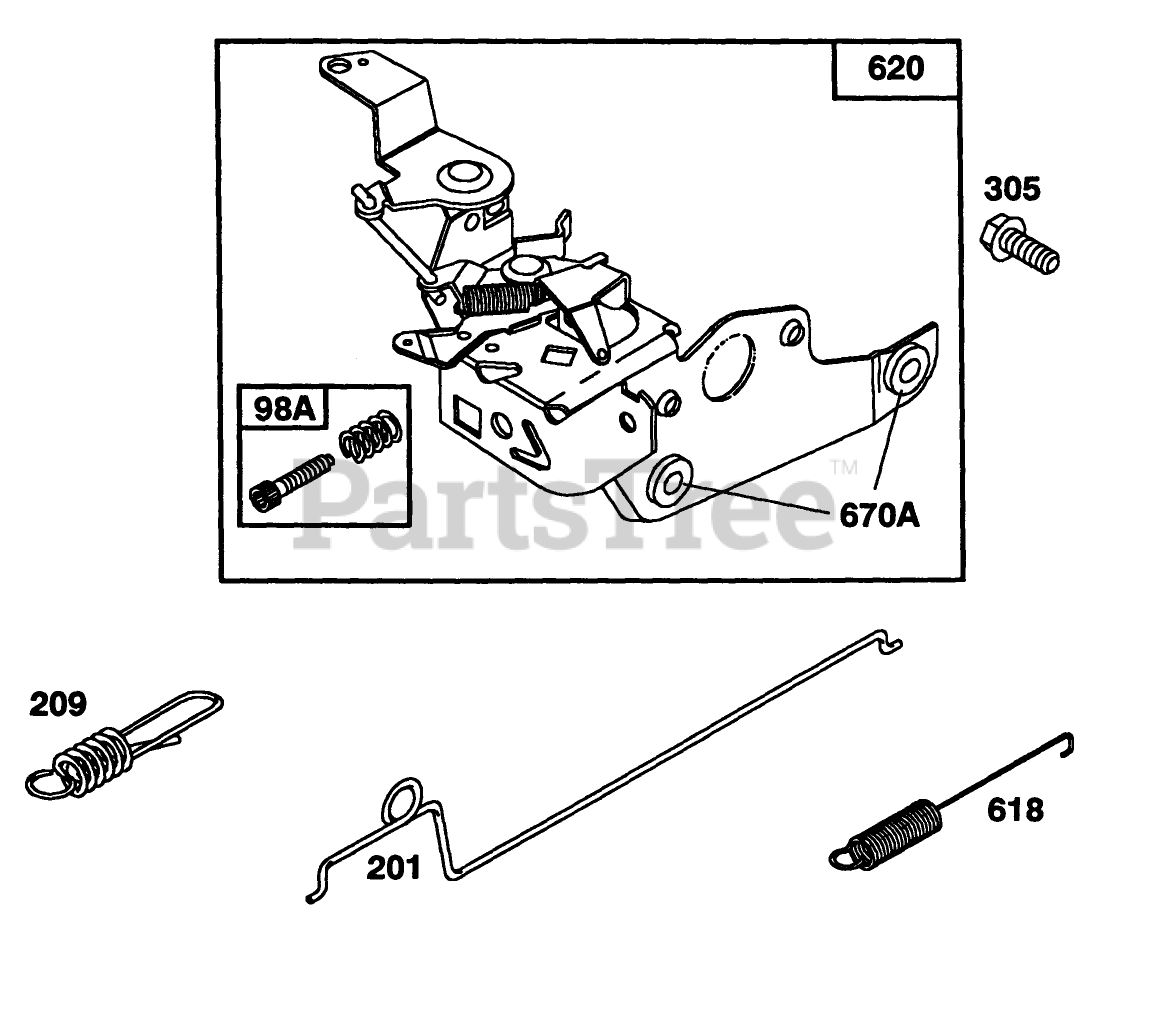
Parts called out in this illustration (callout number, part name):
98A	Screw Assy.
201	Link-Govemor
209	Spring-Govemor
305	Screw-Sem
618	Spring-Choke
620	Bracket Assembly
670A	Spacer
